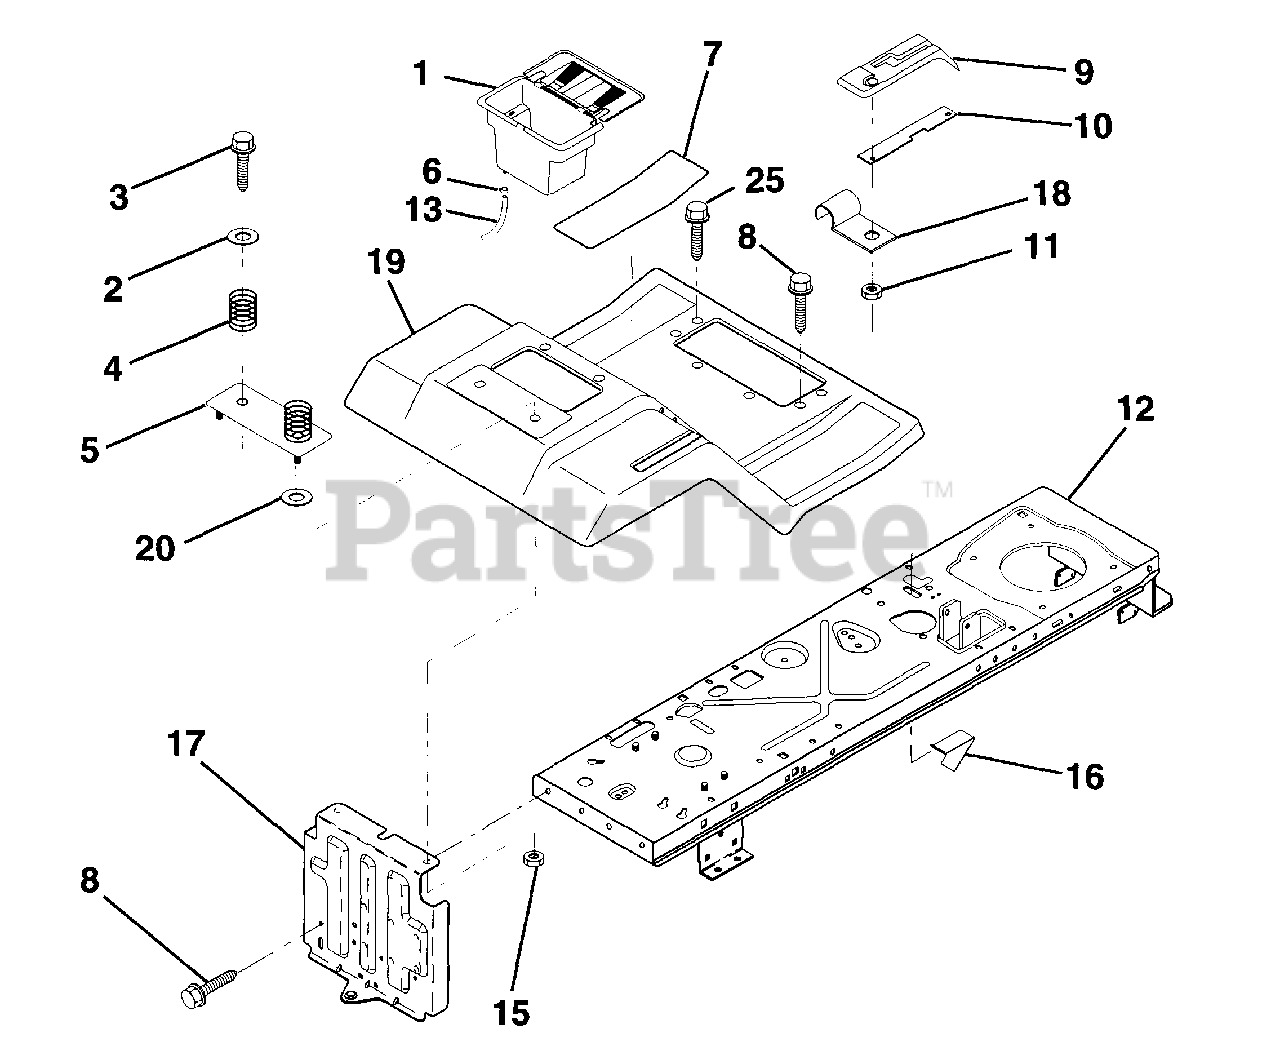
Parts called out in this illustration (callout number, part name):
1	Case, Battery
2	Washer 13/32 x 1-1/4 x 12 Ga.
3	Screw, Hex Wsh. Thrdrol. 3/8-16 x 3/4
4	Spring, Compression, Seat
5	Plate, Asm. Battery
6	Clamp, Hose
7	Pad, Footrest
8	Screw, Hex Wsh Thdrol. 5/16-18 x 3/4
9	Console, Shift Control
10	Bar, Shift Lock
11	Nut, Self-Thrd., Wsh. Head 3/16
12	Assembly, Frame
13	Tube, Battery Drain
15	Nut, Keps Hex 1/4-20 UNC
16	Switch Actuator
18	Clip, Insulated
19	Fender/Footrest
20	Washer 9/32 x 7/8 x 13 Ga.
25	Screw Hex Wsh Thdroll 5/16-18 x 1
